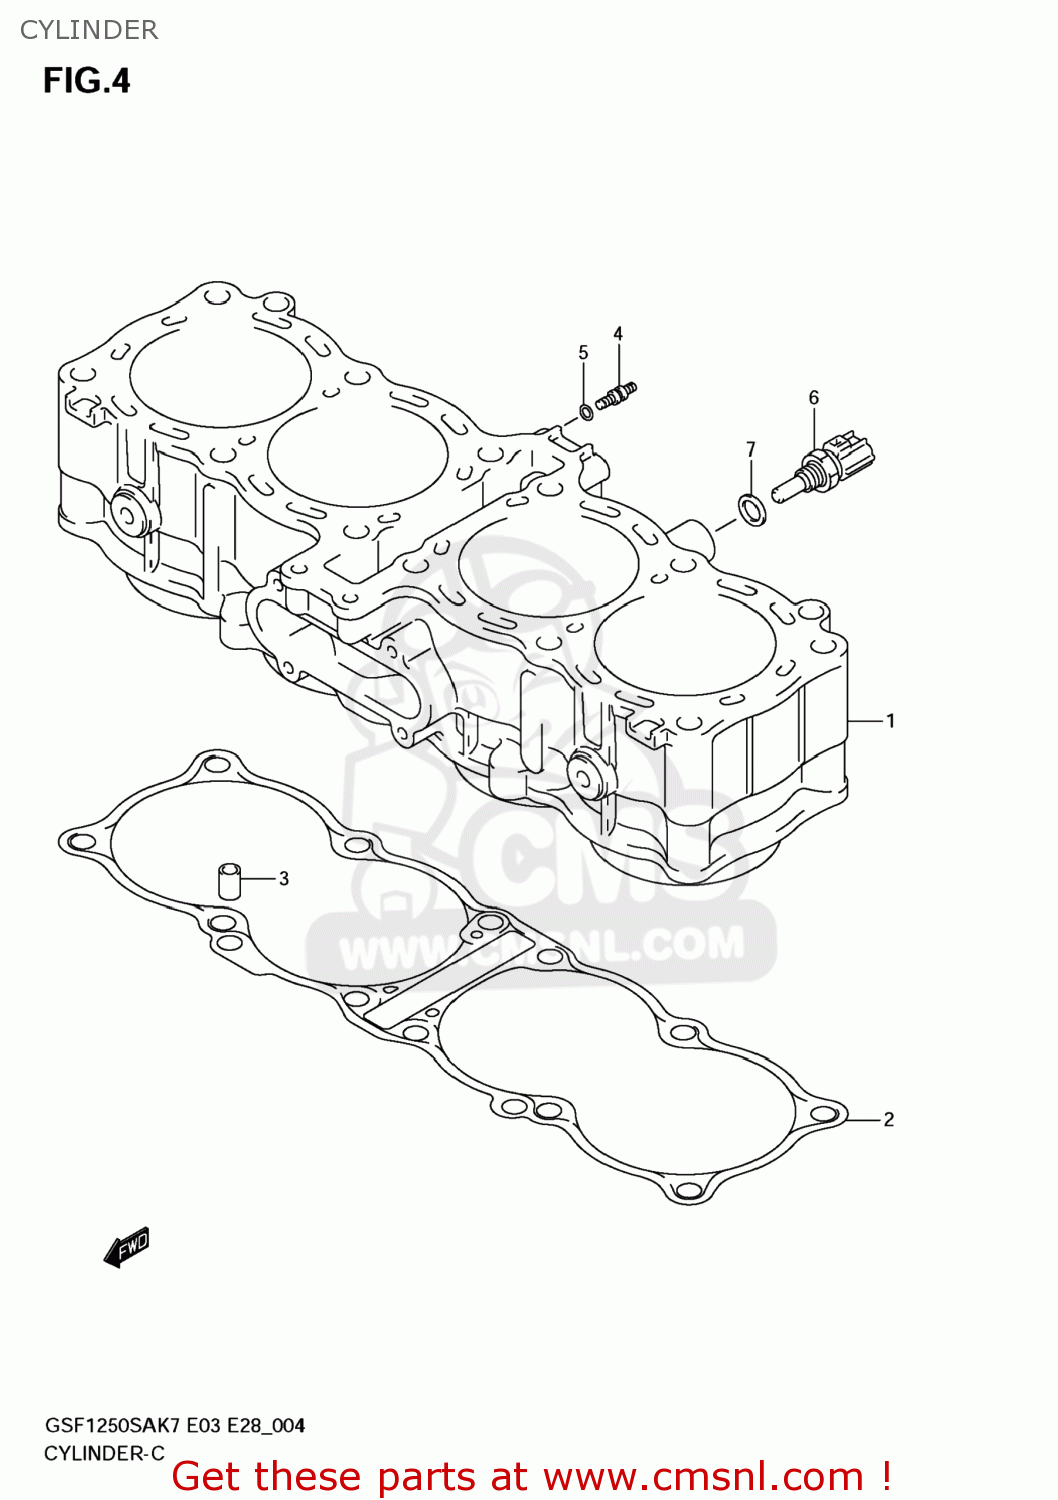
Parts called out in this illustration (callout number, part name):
1	CYLINDER
2	GASKET,CYLINDER (NAS)
3	PIN
4	JET(8)
5	O RING(D:1.2,ID:4)
6	SENSOR,TEMP
7	GASKET(12X17X1) (NAS)
